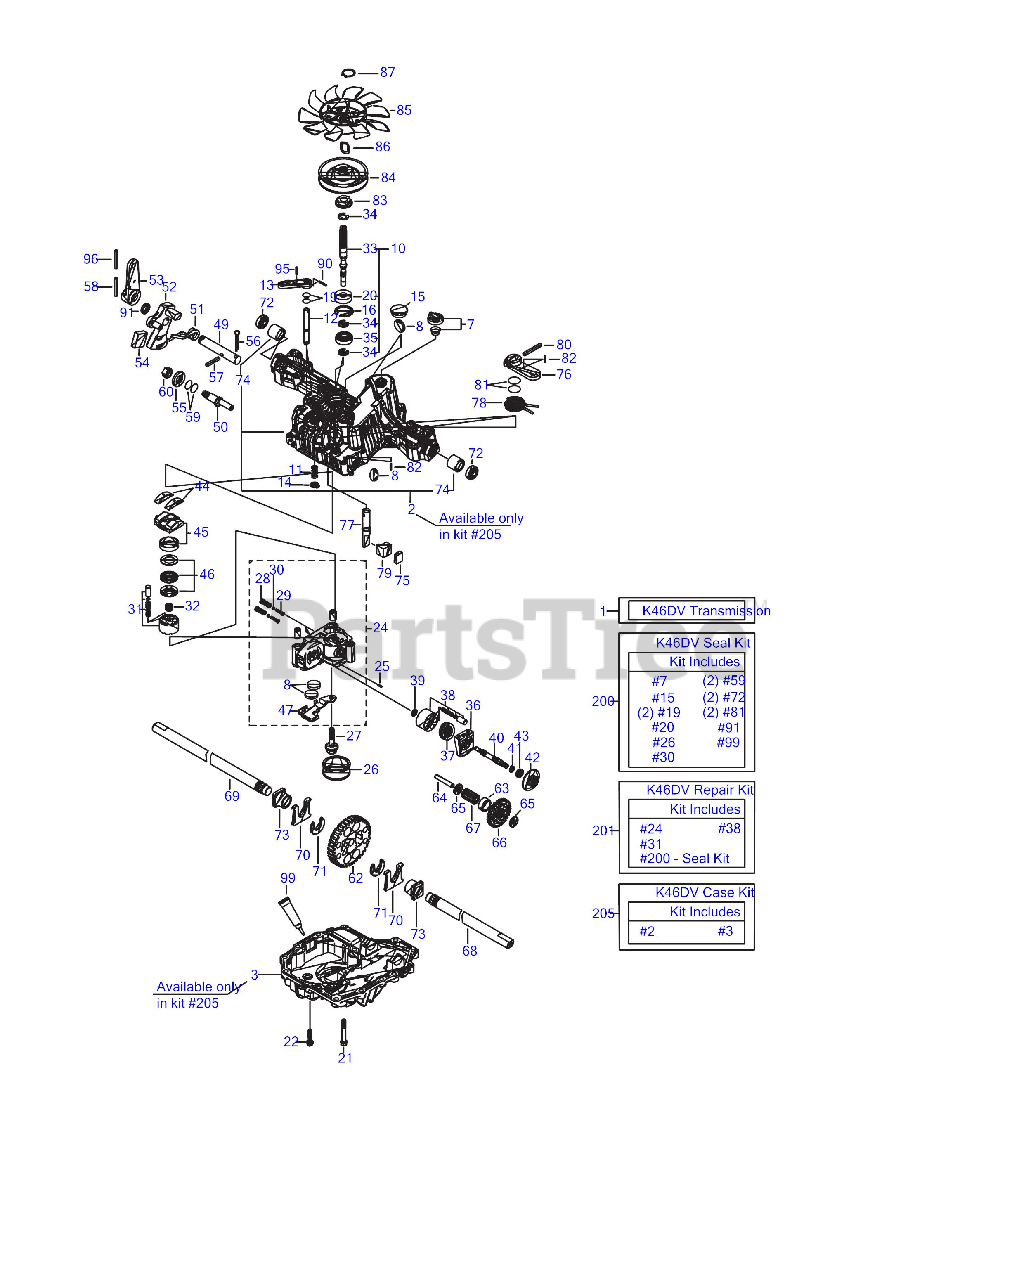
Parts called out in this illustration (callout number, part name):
1	K46DV Transaxle
2	Kit, Housing
3	Lower Case
10	Pump Shaft/Bearing Kit
12	Bypass Shaft A
15	Sealing Cap 30
16	Snap Ring C 35
19	O-Ring 1A P10A
20	Seal TC 153507
21	Tapping Screw 8 x 55
22	Tapping Screw 8 x 30
24	Kit, Center Case
26	Filter 105
28	IDS Valve 1.2
30	IDS Filter 300
31	Kit, Cylinder Block (Pump)
35	Bearing 6202
36	Motor Housing
37	Thrust Bearing 51106
38	Kit, Cylinder Block
39	Washer 12 x 24 x 1
41	Snap Ring S15
42	Brake Disc/Motor Gear
44	Thrust, Plastic
45	Swash Plate Clamp
46	Kit, Thrust Bearing (Pump)
47	Magnet Holder
49	Control Shaft
51	Torsion Spring, Standard
52	Control Lever
53	Control Lever F
56	Cotter Pin 1/8" x 3/4"
57	Spring Pin 6 x 36
58	Roll Pin 6 x 40
62	ETC Diff Comp
63	Final Pinion Collar
64	Reduction Shaft
65	Washer 12 x 32 x 3.2
66	Reduction Gear (37T)
67	Final Pinion Gear (10T)
68	Axle Shaft, Left
69	Axle Shaft, Right
70	Thrust Washer
72	Seal 19 x 32 x 8
73	Bushing 19 x 25
74	Bushing 19.05
78	Brake Return Spring
79	Brake Actuator
80	Spring Pin 5 x 32
81	O-Ring 1A P12
82	Spring Pin 4 x 16
83	Spline Collar
90	Spring Pin 3.0A x 20
91	Oil Seal 16 x 22 x .03
95	Spring Pin 3.0A x 16
96	Roll Pin 3.5 x 40
99	Sealant
200	Kit,Seal Incl. 7, 15, 19, 20, 26, 30,59, 72, 81, 91 & 99
201	Repair Kit, Incl. 24, 31, 38 & 200
205	Housing Kit
